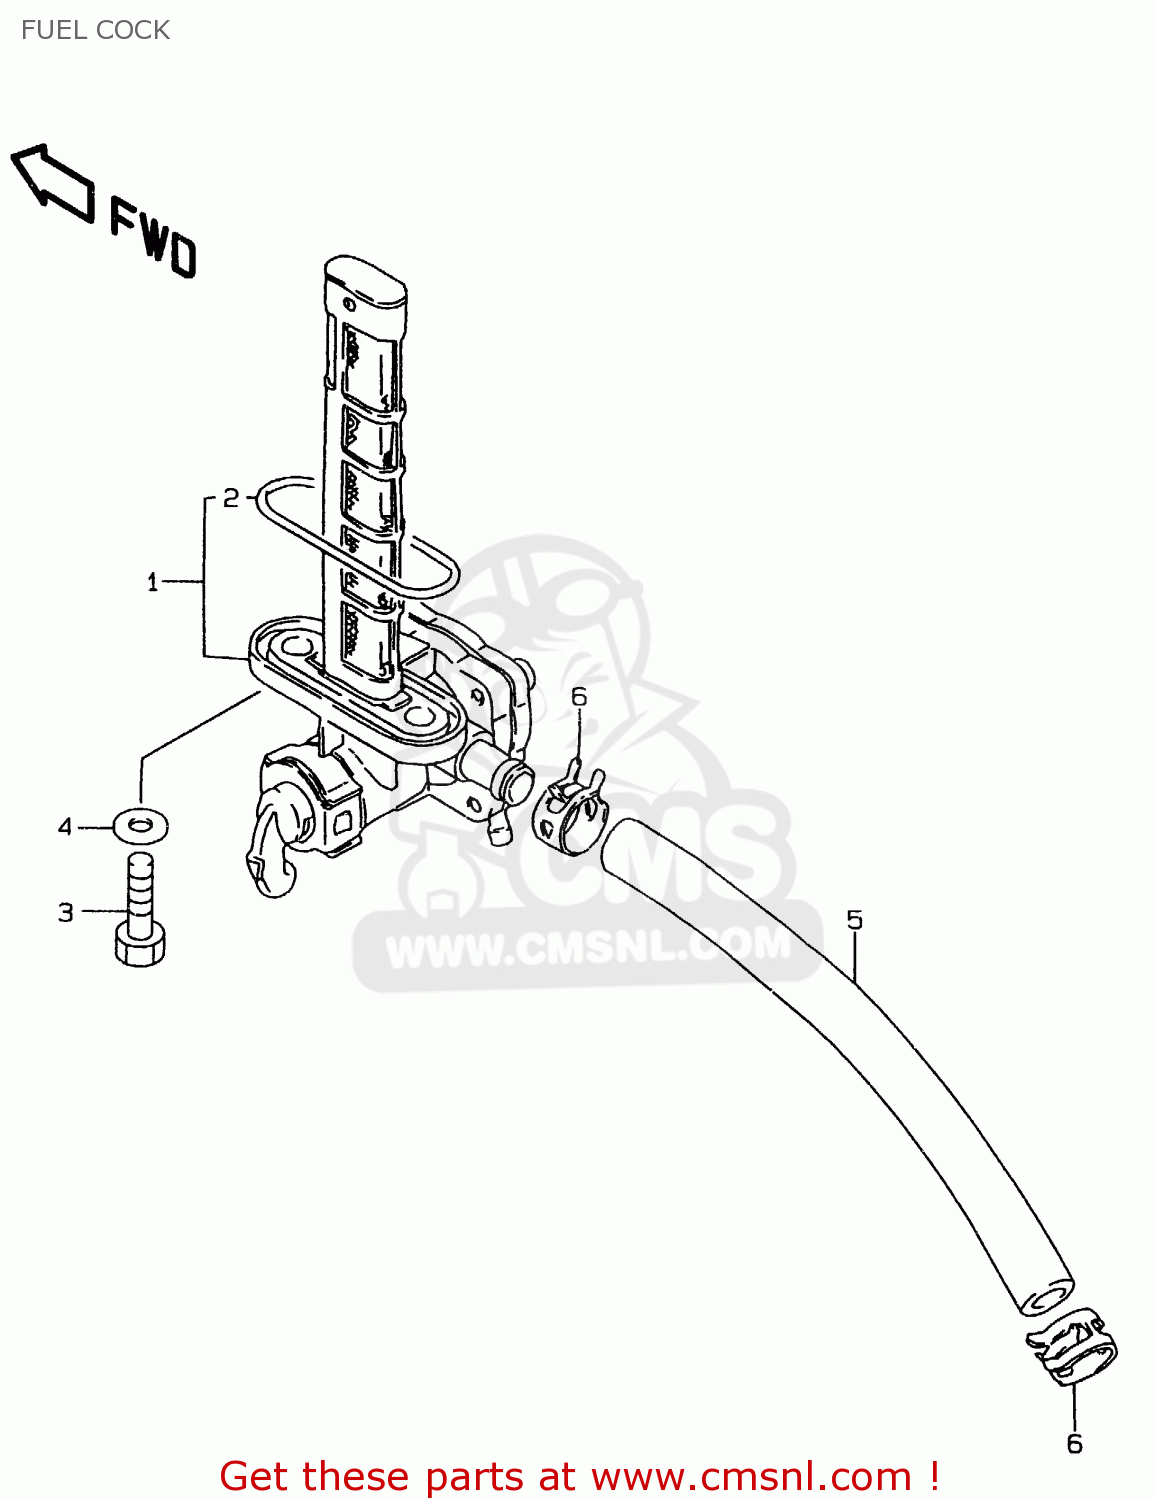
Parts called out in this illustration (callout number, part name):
1	COCK ASSY,FUEL
2	O RING,FUEL COCK
3	BOLT(6X20)
4	GASKET(6.4X11.5X0.8) (NAS)
5	HOSE(7X12X600)
6	CLIP
